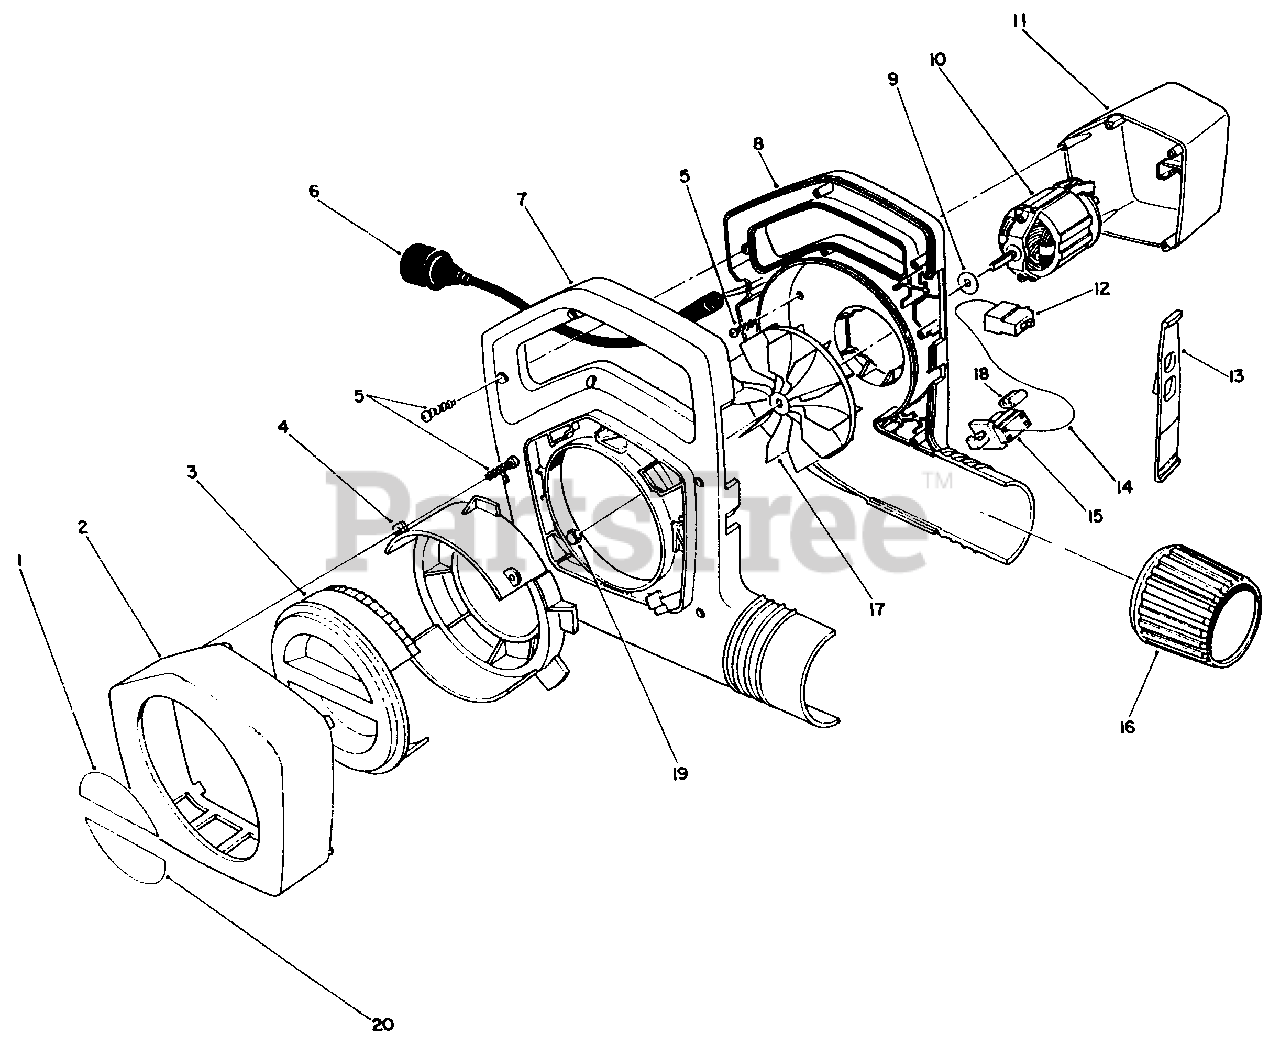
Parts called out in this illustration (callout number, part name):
1	Decal-Choke, Upper
2	Ring-Trim
3	Adjuster-Choke
4	Ring-Tab
5	Screw
6	Cord-Power Supply
7	Housing Assembly-R.H.
8	Housing-L.H.
9	Washer-Impeller
11	Cover-Motor
12	Switch-On/Off
13	Cam-Switch, On/Off
14	Wire-Internal
15	Switch-Interlock
16	Collar-Output
17	Impeller
18	Plug-Dust
20	Decal-Choke, Lower
